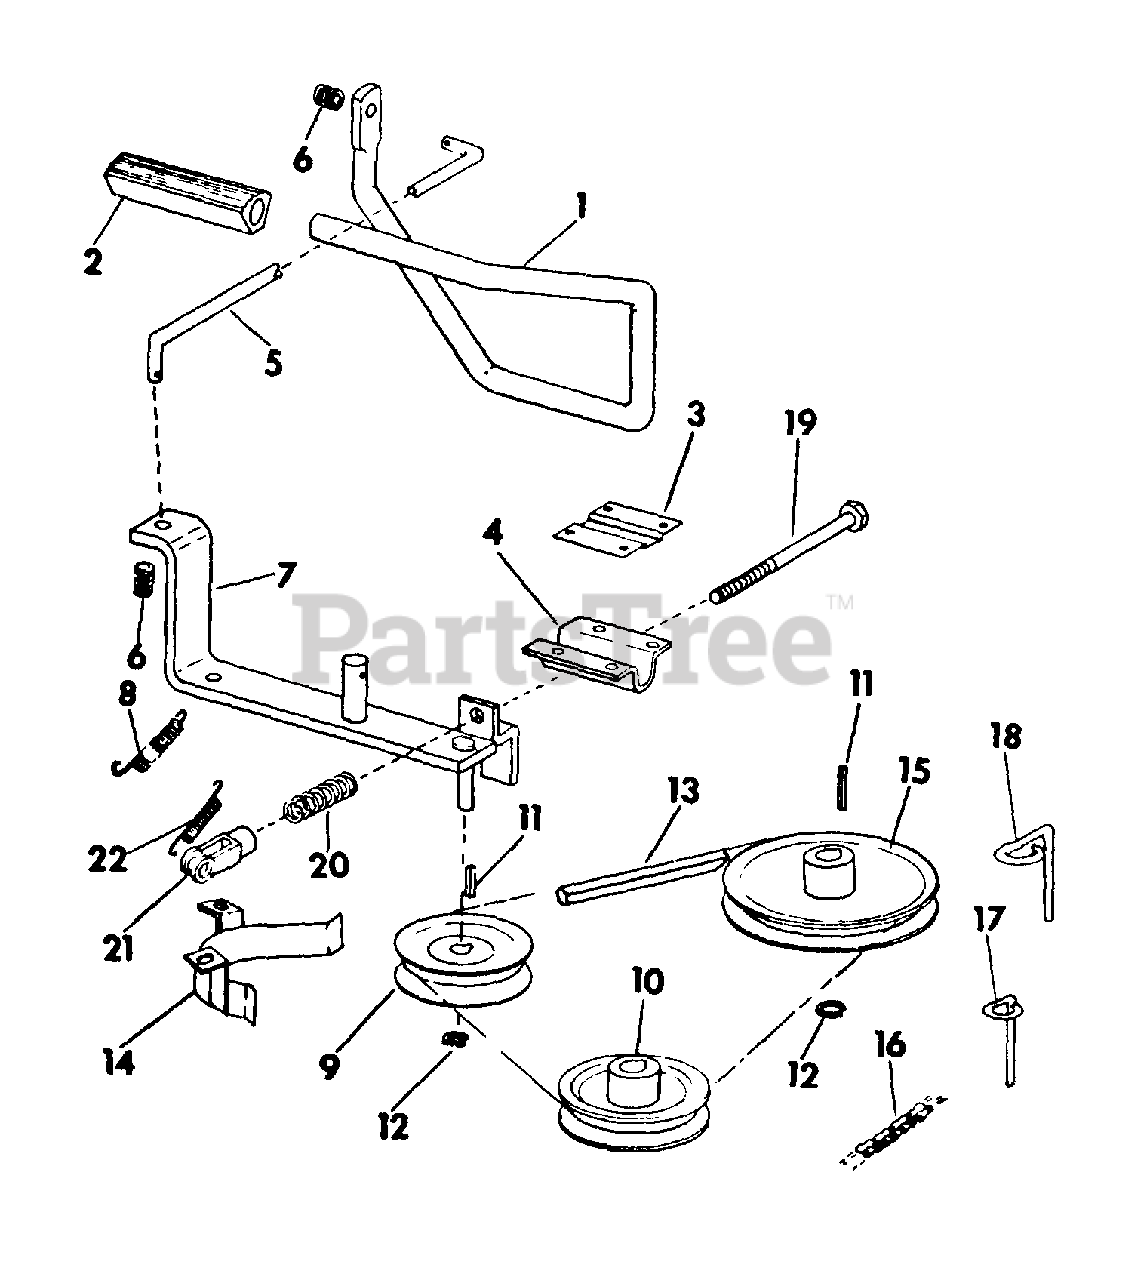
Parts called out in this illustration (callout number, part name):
1	PEDAL, CLUTCH & BRAKE
3	SPRINGER, CLUTCH PEDAL
4	CLAMP, PEDAL PIVOT
5	ROD, CLUTCH CONTROL
6	SPRING, ANTI-RATTLE
7	BAR ASSY, CLUTCH & BRAKE
8	SPRING, PEDAL RETURN
9	PULLEY, IDLER
10	PULLEYS TRACTION MOTOR
11	KEY, 3/16 X 3/4 SAE 9 WOODRUFF
12	RING. EXTERNAL RETAINING - .625 SHAFT
13	BELT, CLUTCHING
14	GUIDE ASSY. BELT
15	PULLEY, TRANS DRIVE
16	CHAIN, FINAL REDUCTION
17	GUIDE, BELT - SHORT
18	GUIDE, BELT - LONG
19	BOLT, BRAKE
20	SPRING, COMPRESSION
21	CLEVIS, 5/16 X 24 C-Z ADJ ROD END
22	SPRING, BRAKE RETURN
